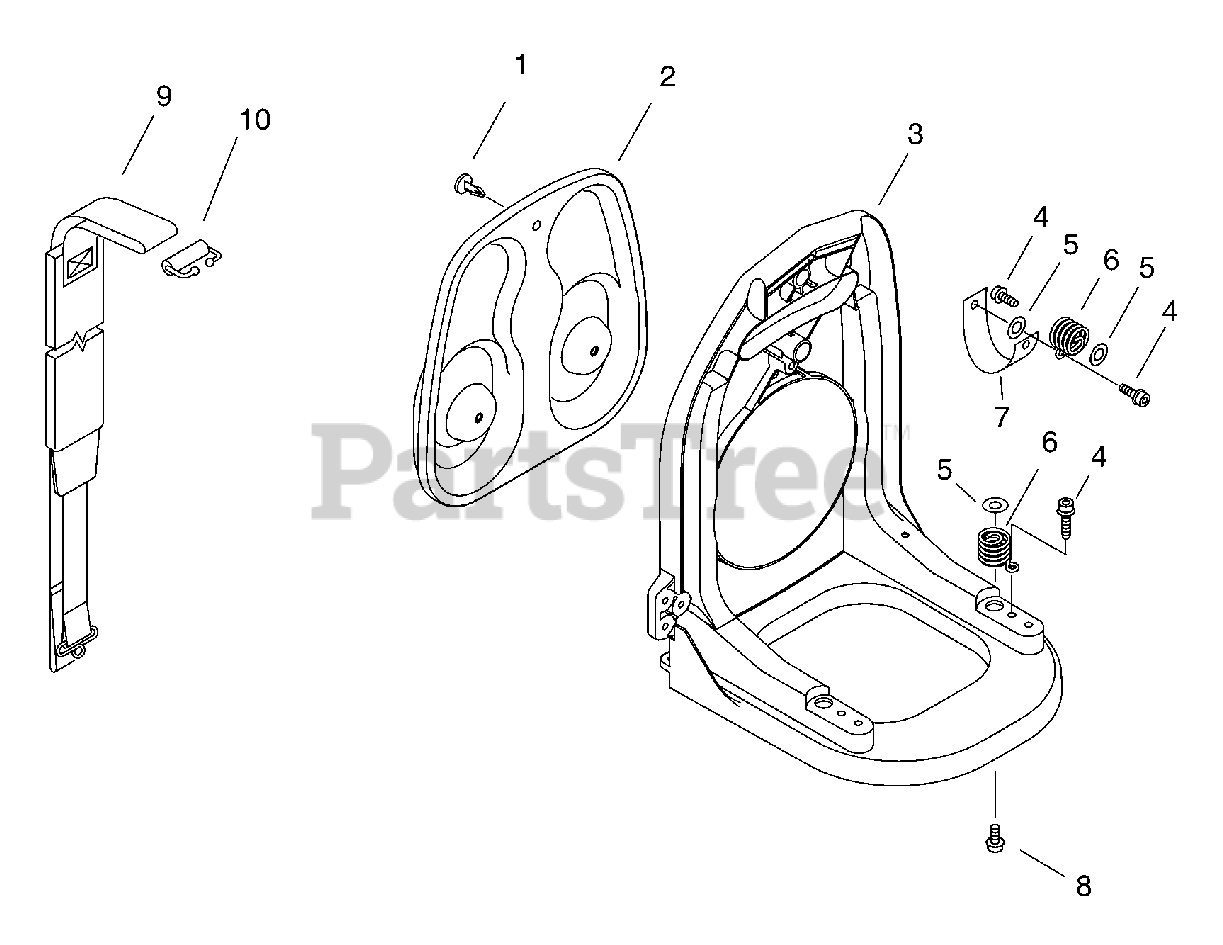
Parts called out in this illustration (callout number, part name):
2	CUSHION, BACKPACK
3	FRAME, BACKPACK
4	SCREW - 5X20
5	WASHER - 5
7	STRAP, SAFETY
8	SCREW - 5X14
9	BACKPACK STRAP ASSY
10	RETAINER, HARNESS
